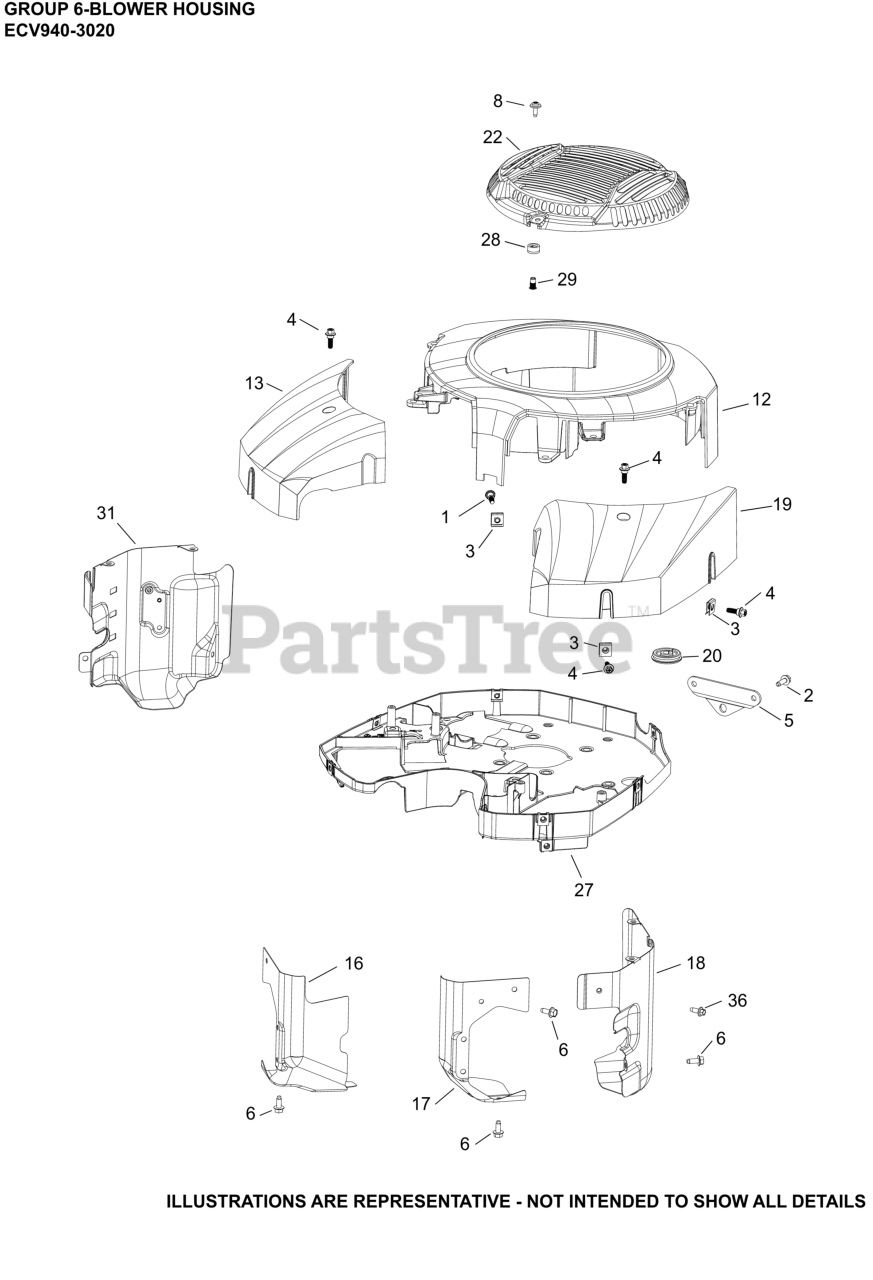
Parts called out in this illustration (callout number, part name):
1	SCREW, SHD THD FRM M6X1X26
2	SCREW, THREAD FORMING
3	CLIP, BAFFLE MOUNTING
4	SCREW, SHD THD FRM
5	STRAP, LIFTING
6	SCREW, THREAD FORMING
8	SCREW, SEMS
12	KIT, BLOWER HOUSING
13	SHROUD, #1 CYLINDER
16	BAFFLE, VALLEY #1 CYLINDER
17	BAFFLE, VALLEY #2 CYL-USE 62 063 40-S
18	BAFFLE, BARREL (#2 CYL)
19	SHROUD, #2 CYLINDER
20	CGROMMET, WIRING HARNESS
22	GUARD, GRASS SCREEN (METAL)
27	SHROUD AND CLIP ASSEMBLY
29	INSERT, THREADED (M5)
31	BAFFLE, BARREL (#1 CYL)
36	SCREW, THREAD FORMING
NI	SCREW, HEX FLANGE
